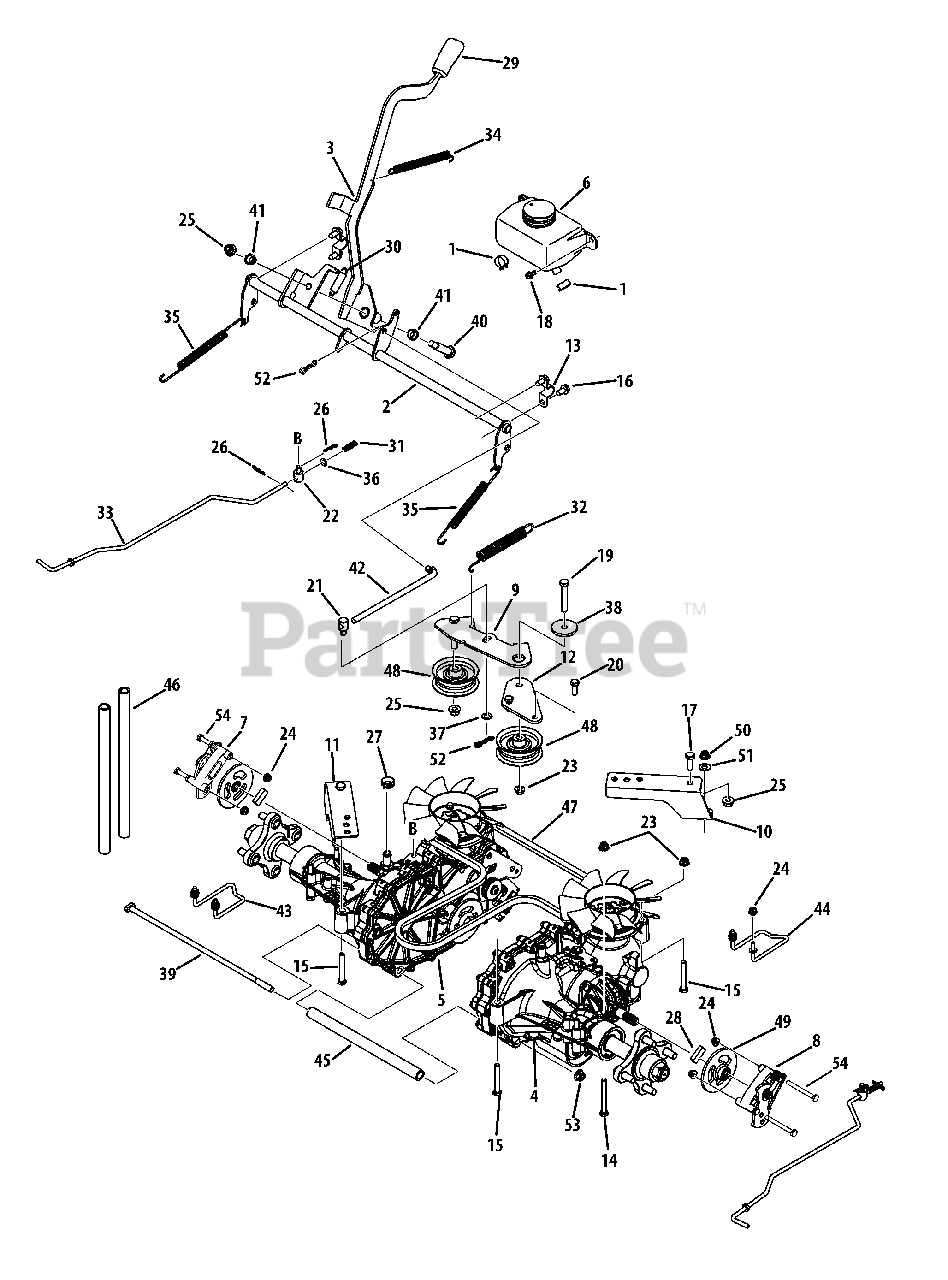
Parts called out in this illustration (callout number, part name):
1	Hose Clamp, 1/2"
2	Brake Shaft Assembly
3	Brake Handle Assembly
4	RH Transmission Assembly
5	LH Transmission Assembly
6	Expansion Tank Assembly
7	LH Brake Assembly
8	RH Brake Assembly
9	Idler Bracket
10	RH Mount Bracket
11	LH Mount Bracket
12	Idler Mount Plate
13	Shaft Mount Bracket
14	Hex Screw, 5/16-18 x 2.75
15	Hex Screw, 5/16-24 x 2.25
16	Hex Washer Screw, 5/16-18 x .750
17	Hex Screw, 3/8-16 x 1.00
18	Hex Washer Screw, 1/4-20 x .500
19	Hex Screw, 3/8-16 x 2.25
20	Hex Screw, 5/16-18 x .875
21	Ferrule, 3/8-24 x .375
22	Ferrule, .325 x .312
23	Flange Lock Nut, 5/16-18
24	Flange Lock Nut, 1/4-20
25	Flange Lock Nut, 3/8-16
26	Cotter Pin, .072 x 1.13
27	Hose Clamp, .75 Dia. x .312
28	Brake Pad
29	Selector Handle
30	Extension Spring, .48 x 2.03
31	Compression Spring, .405 x 1.17
32	Extension Spring, .75 x 6.02
33	Transmission Bypass Lever Wire
34	Extension Spring, .50 x .6.37
35	Extension Spring, .500 x 7.0
36	Spring Washer, .317 x .625 x .020
37	Thrust Washer, .375 x .70 x .030
38	Shoulder Spacer, .884 x .190
39	Rod, .405 x 14.00
40	Shoulder Screw, .498 x 1.635
41	Flange Bearing, .500 x .34
42	Disenage Brake Rod
43	LH Rod Keeper
44	RH Rod Keeper
45	Transmission Spacer, 10.5
46	Fuel Hose, 1/2 x 12.00
48	Flat Idler Pulley, 2.75
49	Brake Disc
50	Hex Lock Nut, 5/16-24
51	Flat Washer, .330 x .630 x .064
52	Bow-Tie Cotter Pin
53	Flange Lock Nut, 7/16-20
54	Hex Screw, 1/4-20 x 2.50
